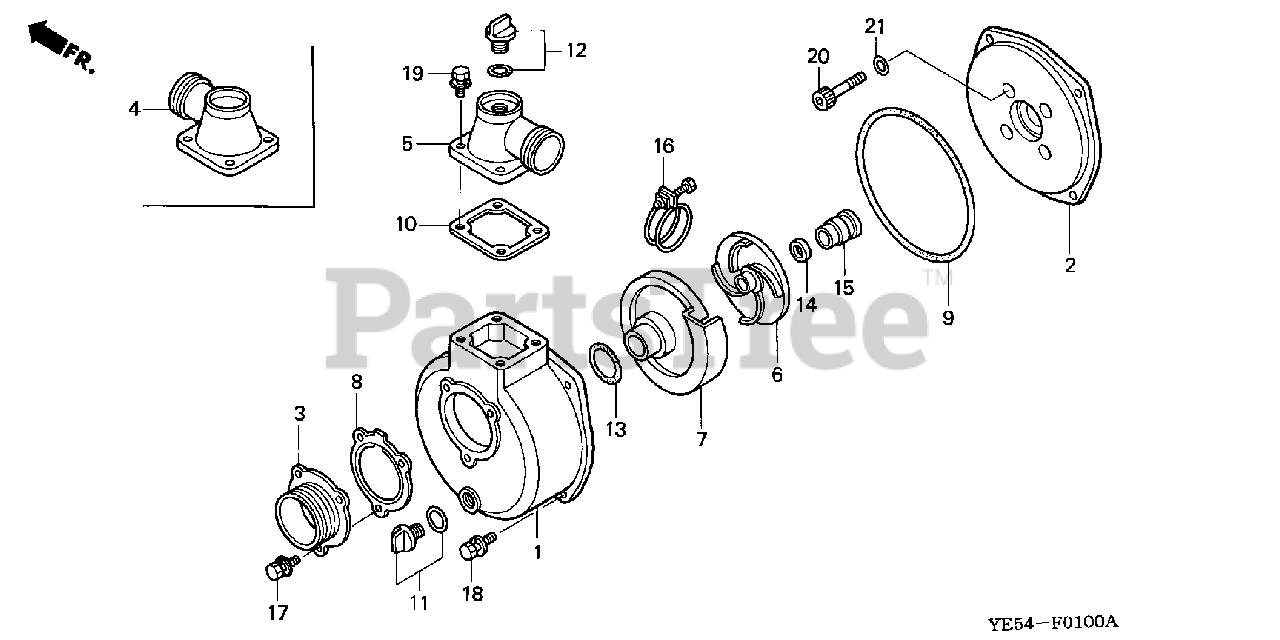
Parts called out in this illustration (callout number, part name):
1	CASING
2	COVER, CASING
3	INLET (NPT)
4	OUTLET (NPT)
7	CASE, VOLUTE
8	VALVE, IN.
9	RING, CASING SEAL
10	GASKET, OUTLET
11	CAP, FILLER
12	CAP, FILLER
13	O-RING (53.6X5.7)
14	SHIM, ADJUSTER
15	SEAL, MECHANICAL
16	BAND, HOSE
17	BOLT-WASHER (8X20)
18	BOLT-WASHER (8X22)
19	BOLT-WASHER (8X25)
20	BOLT, SOCKET (8X60)
21	WASHER, SEAL
